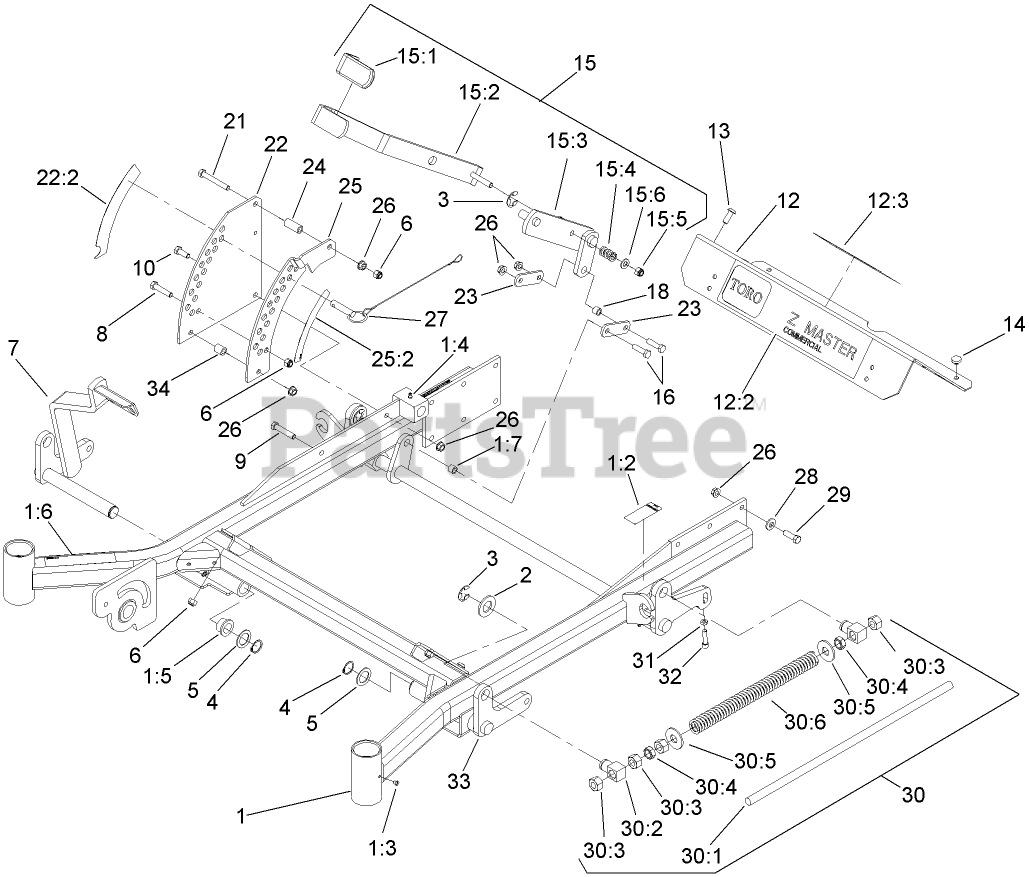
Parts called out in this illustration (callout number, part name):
1	Frame ASM
1:2	Decal-Brake, Parking
1:4	FITTING-GREASE
1:5	BUSHING
1:6	DECAL-WARNING
1:7	Bushing
2	WASHER-FLAT
3	RING-RETAINING, EXT
4	RING-RETAINING
5	WASHER-SPACER
6	NUT-LOCK, NI
7	LIFT-DECK, RH FRONT
8	SCREW-HH
9	SCREW-HH
10	SCREW-HH
12	FOOTREST
12:3	DECAL-WARNING
13	SCREW-HSBH
14	BUMPER
15	DECK LIFT HANDLE ASM
15:1	GRIP-LEVER, LIFT
15:2	LEVER-LIFT
15:3	ARM-LIFT, DECK
15:4	SPRING-COMPRESSION
15:5	NUT-LOCK, NI
15:6	WASHER-FLAT
16	SCREW-HH
18	Bushing
21	SCREW-HH
22	PLATE-DECK LIFT, OUTER
22:2	Decal-Height, Deck
23	ARM-LIFT, DECK
24	BUSHING-LEVER, LIFT
25	PLATE-DECK LIFT, INNER
25:2	Decal-Height, Deck
26	NUT-HHF, WHIZ
27	Hitch Pin ASM
28	WASHER-BELLEVILLE
29	SCREW-HH
30	Front Frame Spring ASM
30:1	ROD-LIFT, DECK
30:2	SWIVEL-DECK MOUNT, REAR
30:3	NUT-HEX
30:4	NUT-JAM
30:5	WASHER-FLAT
30:6	SPRING-SUPPORT, DECK
31	NUT-JAM
32	SCREW-HSH
33	LIFT-DECK, LH
34	BUSHING-LEVER, LIFT
